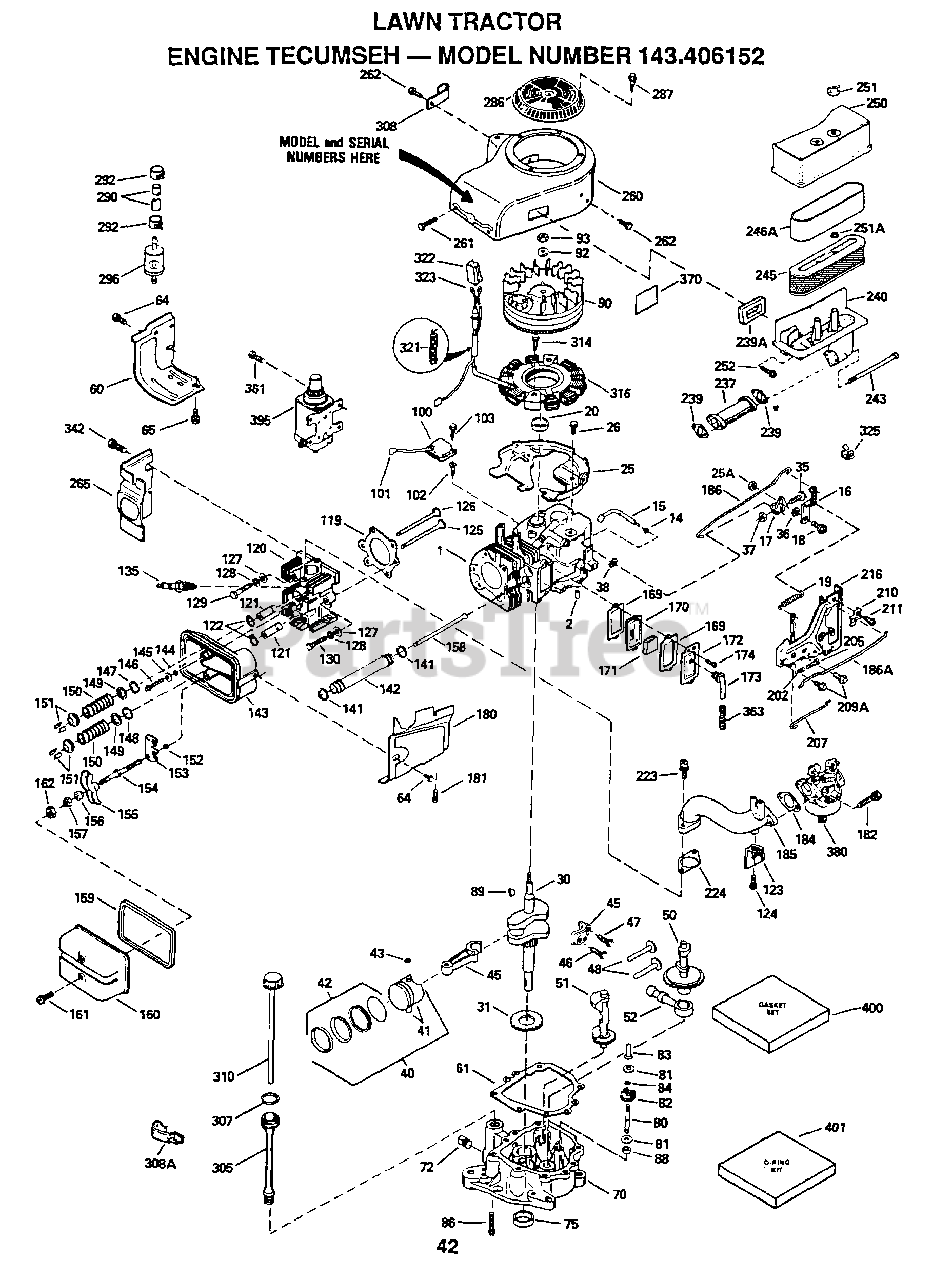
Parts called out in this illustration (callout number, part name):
1	CYLINDER ASSY
2	PIN, DOWEL
15	ROD, GOVERNOR
16	LEVER, GOVERNOR
17	CLAMP, THROTTLE LEVER
18	SCREW
19	SPRING, CONTROL
20	SEAL, OIL
25	BAFFLE, BLOWER HOUSING
25A	NUT & WASHER
30	CRANKSHAFT ASSY
31	GEAR, COUNTERBALANCE
37	NUT, LOCK
38	RING, RETAINING
40	PISTON, PIN & RING ASSY
40A	PISTON, PIN & RING ASSY
40B	PISTON, PIN & RING ASSY
41	PISTON & PIN ASSY
41A	PISTON & PIN ASSY
41B	PISTON & PIN ASSY
42	RING SET, PISTON
42A	RING SET, PISTON
42B	RING SET, PISTON
43	RING, PISTON PIN RETAINING
45	ROD ASSY, CONNECTING
46	BOLT, CONNECTING ROD
47	BOLT, CONNECTING ROD
48	LIFTER, VALVE
50	CAMSHAFT
51	WEIGHT ASSY, COUNTERBALANCE
52	PUMP ASSY, OIL
60	EXTENSION, BLOWER HOUSING
61	GASKET, MOUNTING FLANGE
70	FLANGE, MOUNTING
72	PLUG, OIL DRAIN
75	SEAL, OIL
80	SHAFT, GOVERNOR
81	WASHER, FLAT
82	GEAR ASSY, GOVERNOR
83	SPOOL, GOVERNOR
84	RING, RETAINING
88	SPACER, GOVERNOR GEAR
89	KEY, FLYWHEEL
90	FLYWHEEL
92	WASHER, LOCK
93	NUT, FLYWHEEL
100	SOLID STATE ASSY
101	SPARK PLUG COVER
102	STUD, SOLID STATE ASSY
103	SCREW
119	GASKET, CYLINDER HEAD
120	HEAD ASSY, CYLINDER
121	VALVE GUIDE KIT
122	RING, RETAINER
123	BRACE, INTAKE PIPE
125	VALVE, EXHAUST
125A	VALVE, EXHAUST
126	VALVE, INTAKE
126A	VALVE, INTAKE
127	WASHER, FLAT
128	WASHER, BELLEVILLE
135	RESISTOR SPARK PLUG
142	TUBE, PUSH ROD
143	HOUSING, ROCKER ARM
145	WASHER, FLAT
146	CONNECTING ROD BOLT
149	CAP, VALVE SPRING
150	SPRING, VALVE
151	CAP, VALVE SPRING KEEPER
153	GUIDE, PUSH ROD
154	STUD, ROCKER ARM
155	ARM, ROCKER
156	BEARING, ROCKER ARM
157	NUT ASSY, LOCK
158	ROD, PUSH
159	O-RING ASSY
160	COVER, ROCKER ARM HOUSING
162	NUT, HEX JAM
169	GASKET, VALVE COVER
170	BODY, BREATHER
171	ELEMENT, BREATHER
172	COVER, VALVE SPRING BOX
173	TUBE, BREATHER
180	EXTENSION, BLOWER HOUSING
184	GASKET, CARBURETOR TO INTAKE PIPE
185	PIPE, INTAKE
186	LINK, GOVERNOR
186A	LINK, CHOKE
202	SPRING, COMPRESSION
205	SCREW
207	LINK, CONTROL BRACKET
210	CLIP, CONDUIT
216	BRACKET ASSY
